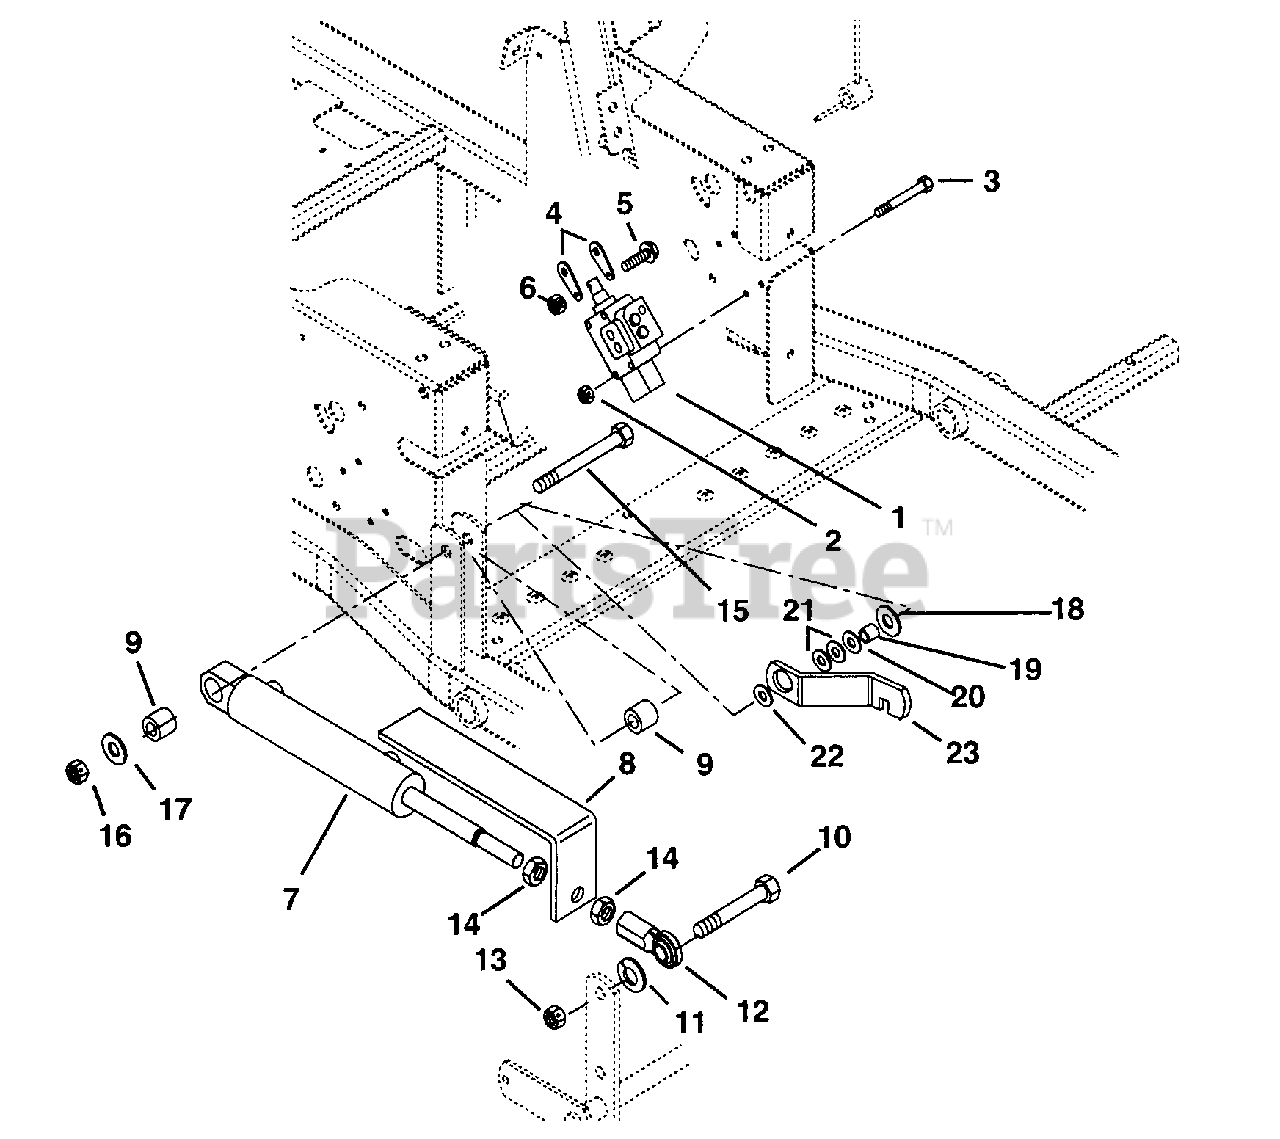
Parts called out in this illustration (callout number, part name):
1	Valve, Hydraulic Lift
2	Nut-Locking-Nylon .25-20
3	Bolt-Hex .25-20 x 2.75 Grade 5
5	Screw-Machine 10-24 x 1.00 Hex Washer Head
6	Nut-Locking-Nylon 10-24 with Insert
7	Cylinder-Hydraulic Lift
8	Strap-Height of Cut Indicator
9	Bushing .516 x 1.000 x 1.050
10	Bolt-Hex .62-11 x 2.25 Grade 8
11	Washer-Lock .62 x .156
12	Rod End-Right Hand-Female 5/8
13	Nut-Locking-Center .62-11
14	Nut-Jam .625-18
15	Bolt-Hex .50-13 x 3.75 Grade 5
16	Nut-Locking-Center .50-13
17	Washer-Flat-Steel .515 x 1.625 x .250
18	Washer-Flat-Steel .531 x 1.06 x .095
19	Spacer .500 x .750 x .321
20	Washer-Flat-Steel .754 x 1.000 x .032
21	Washer-Flat-Steel .754 x 1.125 x .062
22	Wave-Washer
